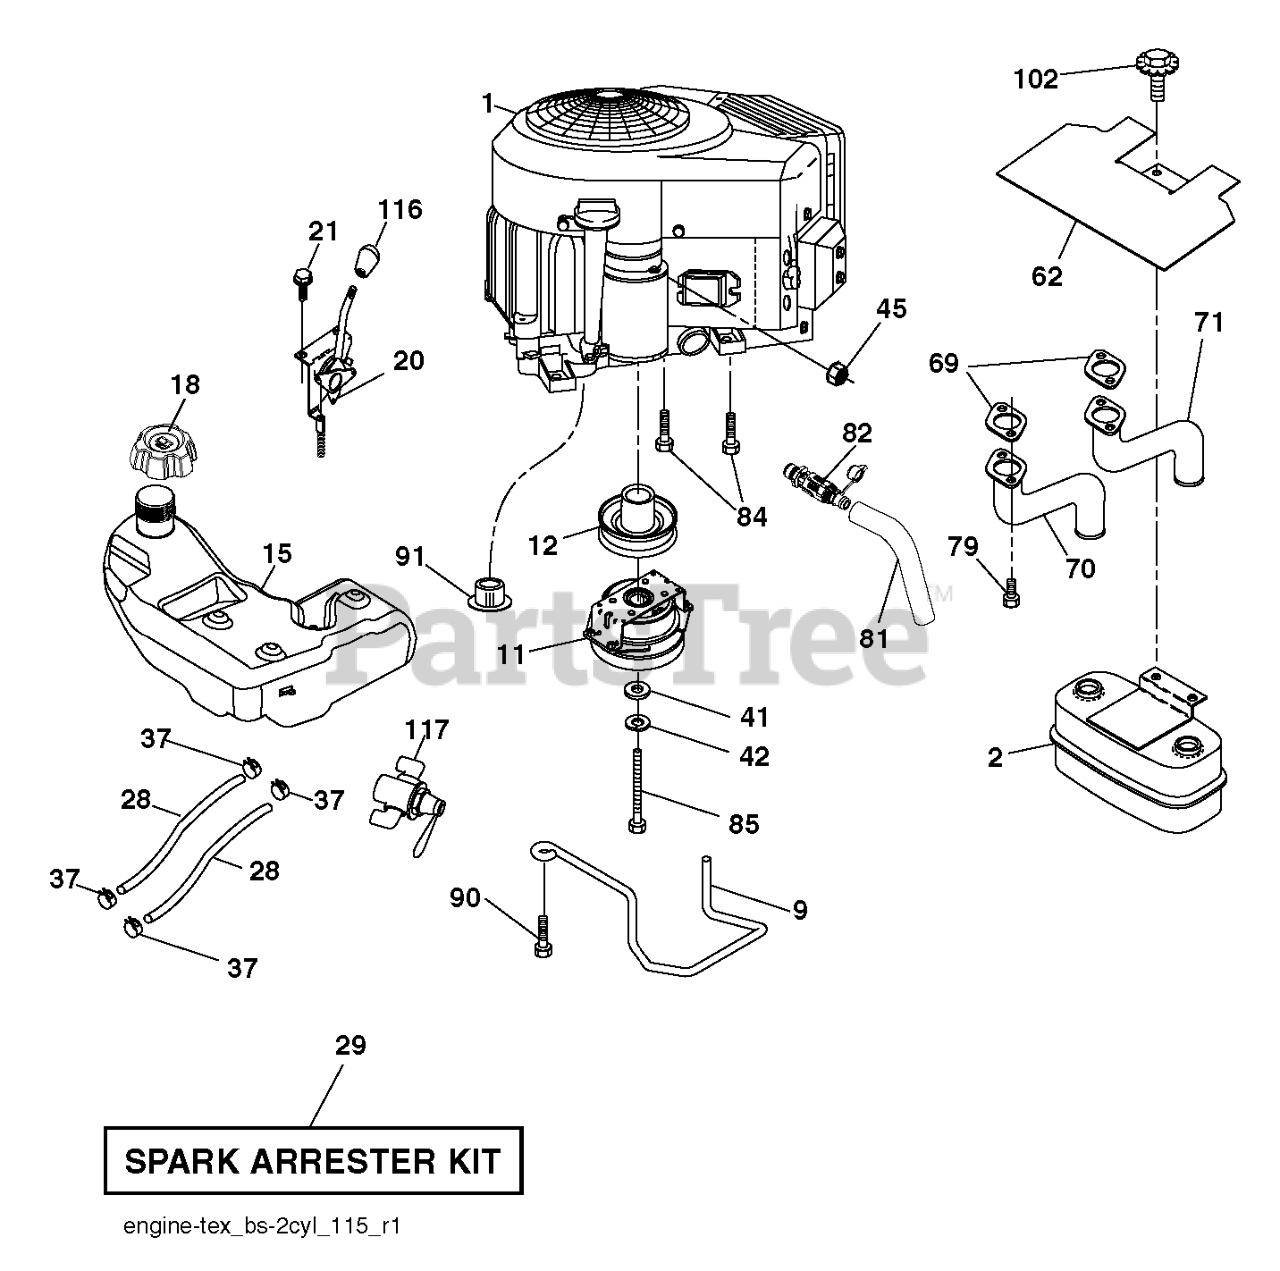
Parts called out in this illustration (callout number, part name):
2	MUFFLER.ASM.TWN.EXTNDED.DFLCTR
9	KEEPER BELT ENGINE
11	CLUTCH MZ ZTR GT.48/54"1.125"
12	PULLEY ENGINE
15	RP_TANK.ASSY.4.GAL.2.PORT.EPA
18	CAP.ASM.FL.RITCH.3"E10.SYM.498
20	CONTROL.THROTTLE/CHOKE.PRO.45
21	SCREW.#10 X 0.750.BOS
28	LINE.FUEL.64"REAR.EMIS
29	KIT.SPARK ARRESTOR 794945 B&S
37	HOSE CLAMP
42	LOCKWASHER
45	NUT
62	SHIELD.HEAT.MUFFLER
69	GASKET.MUFFLER
70	EXHAUST.TUBE.LH.BS/TWIN
71	EXHAUST.TUBE.RH.B&S.TWIN.INTEK
79	SCREW.SOCKET.HEAD.5/16-18
81	TUBE, DRAIN OIL ASM.
82	VALUE.OIL.DRAIN
84	SCREW.3/8-16
85	BOLT HEX 7/16-20 X 3.75 GR. 5
87	BOLT.5/16-18UNCX3/4 W/SEMS.BLK
90	SCREW 3/8-16X1
91	BUSHING.1.375OD
116	KNOB - SHIFT
117	VALVE FUEL RESERVE
